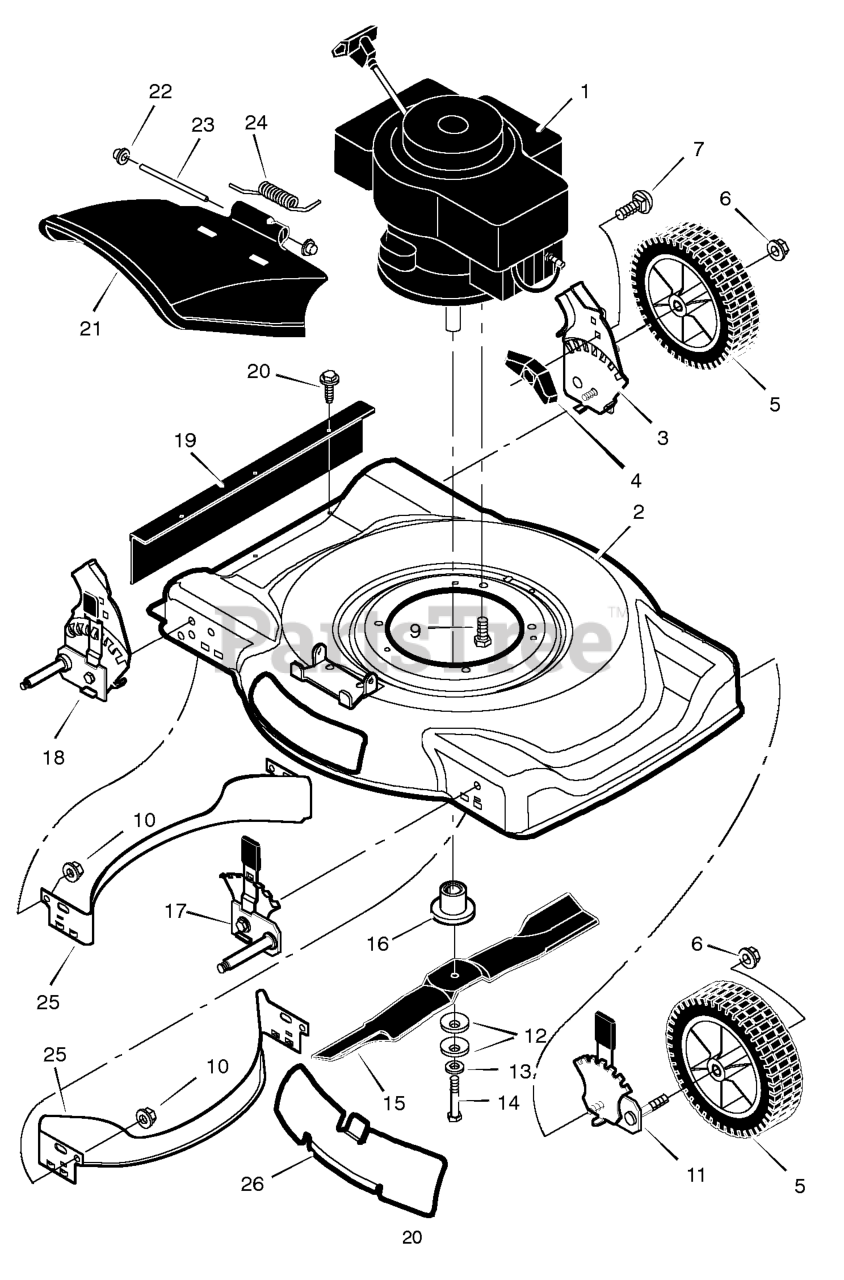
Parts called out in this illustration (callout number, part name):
1	Engine *
2	Housing
3	Height Adjuster, Left Rear
5	Wheel and Tire *
6	Locknut, Flange
7	Bolt, Carriage
9	Bolt, Engine
10	Nut
11	Height Adjuster, Left Front
12	Washer, Belleville
14	Bolt, Hex
16	Adapter, Blade
17	Height Adjuster, Right Front
18	Height Adjuster, Right Rear
19	Guard, Rear
21	Deflector, Chute
22	Push- On Cap
23	Pin, Pivot
26	Plate, Mulch
